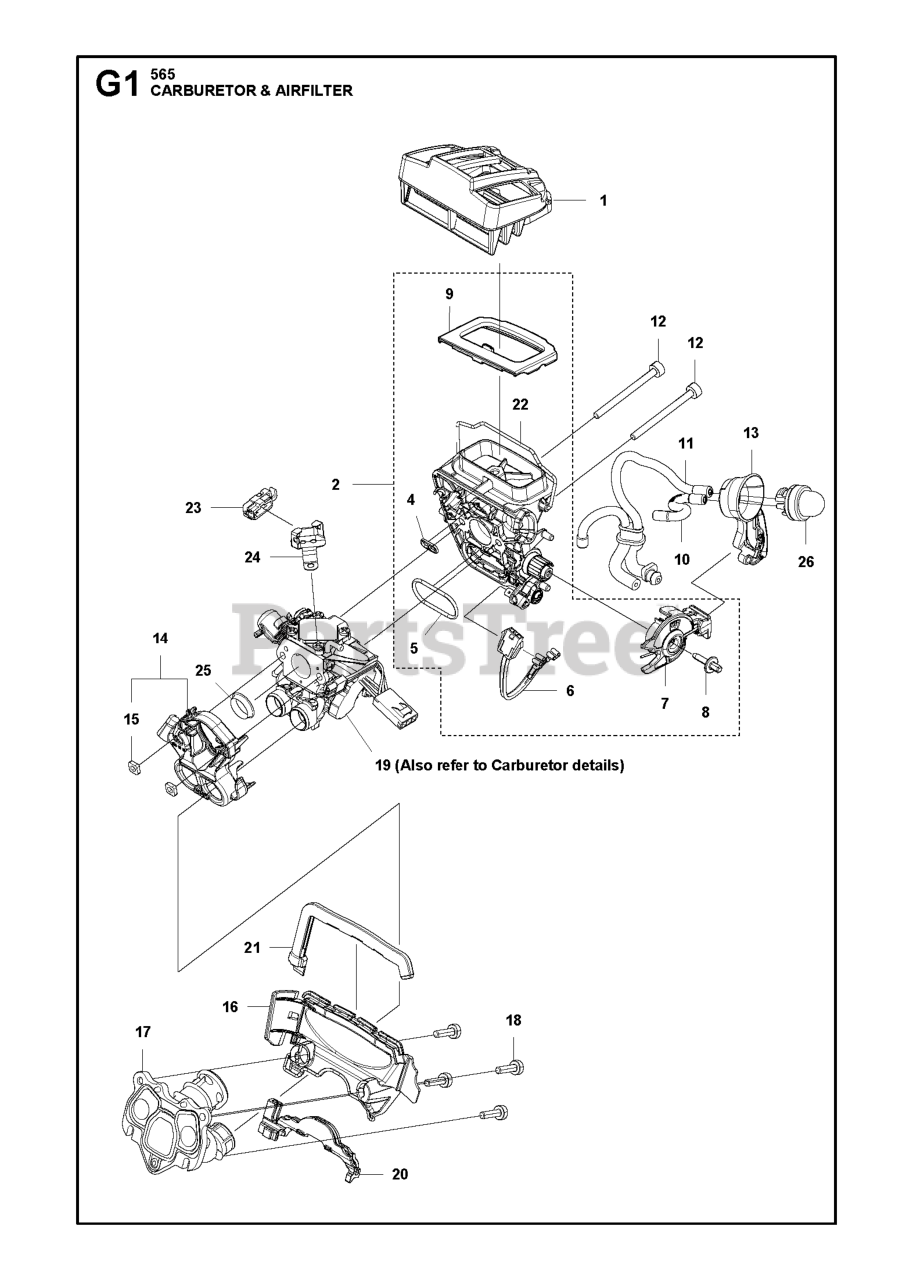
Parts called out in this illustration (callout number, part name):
1	AIR FILTER ASSY H565 64 MICRON
1	AIR FILTER ASSY H565 25 MICRON
1	AIR FILTER ASSY H565 NW
2	INLET ELBOW STANDARD SPARE PAR
6	WIRING ASSY STOP
7	CHOKE CONTROL ASSY CHOKE/STOP
9	SEALING FILTER HOLDER
11	FUEL HOSE PURGE/TANKVENTILATIO
12	SCREW ITXSCFM M4X50 T20 12.9
14	FLANGE CARBURETTOR FLANGE
16	BAFFLE INTERMEDIATE WALL INTER
17	INLET PIPE H565/H572 STD
17	INLET PIPE H565/H572 COLD
18	SCREW ITXSCM M4X15 T27 12.9 T
19	CARBURETTOR KIT 565XP
20	SEALING INLET PIPE
21	SEALING BAFFLE
23	CONTACT CLAMP
24	RETAINER CONTACT CLAMP
25	SUPPORT SLEEVE
26	AIR PURGE BUBBLE
